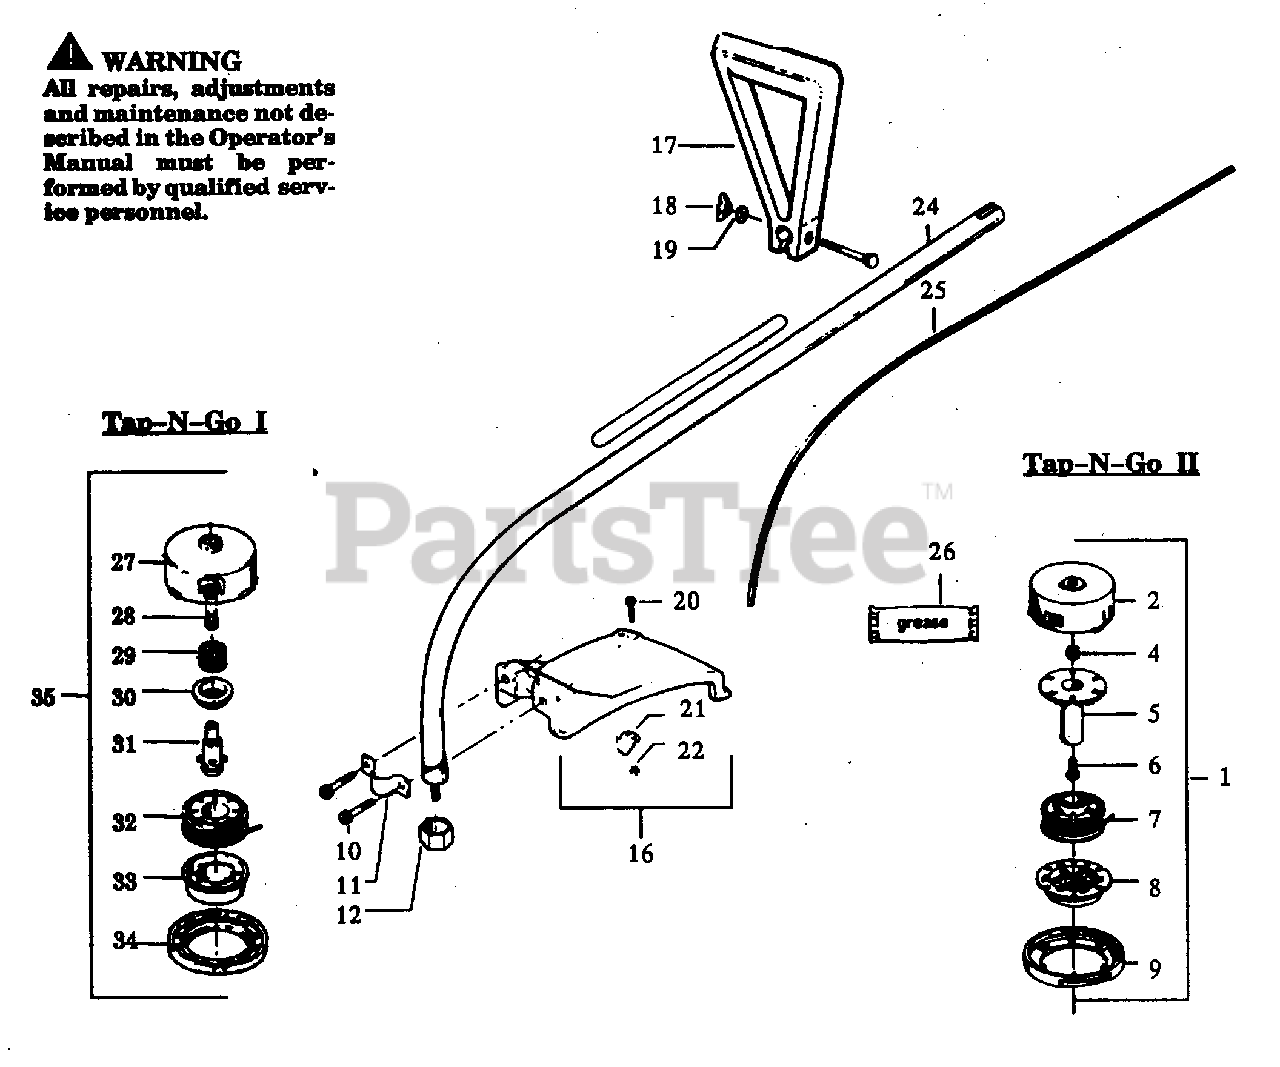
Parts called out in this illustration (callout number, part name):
1	Cutting Head Ass'y.(Inc.2,4 & 5-9) See Service Ref. 1
2	Hub w/Line Saver
4	Spring
5	Spool Post
7	Spool w/Line
8	Release Button
10	Screw
12	Dust Cup
16	Shield Kit Ass'y. (Inc.10,20,21,22)
17	Assist Handle
18	Wing Nut
21	Line Limiter
22	Nut
24	Drive Shaft Hsg.
25	Drive Shaft
26	Shaft Lubrication
27	Hub w/Line Saver
28	Line Saver
29	Spring
30	Spring Adaptor
31	Drive Gear
32	Spool w/Line
33	Release Button
35	Cutting Head Assy.(Inc.27-34)See Service Ref. 1
A	Safety Label Decal
